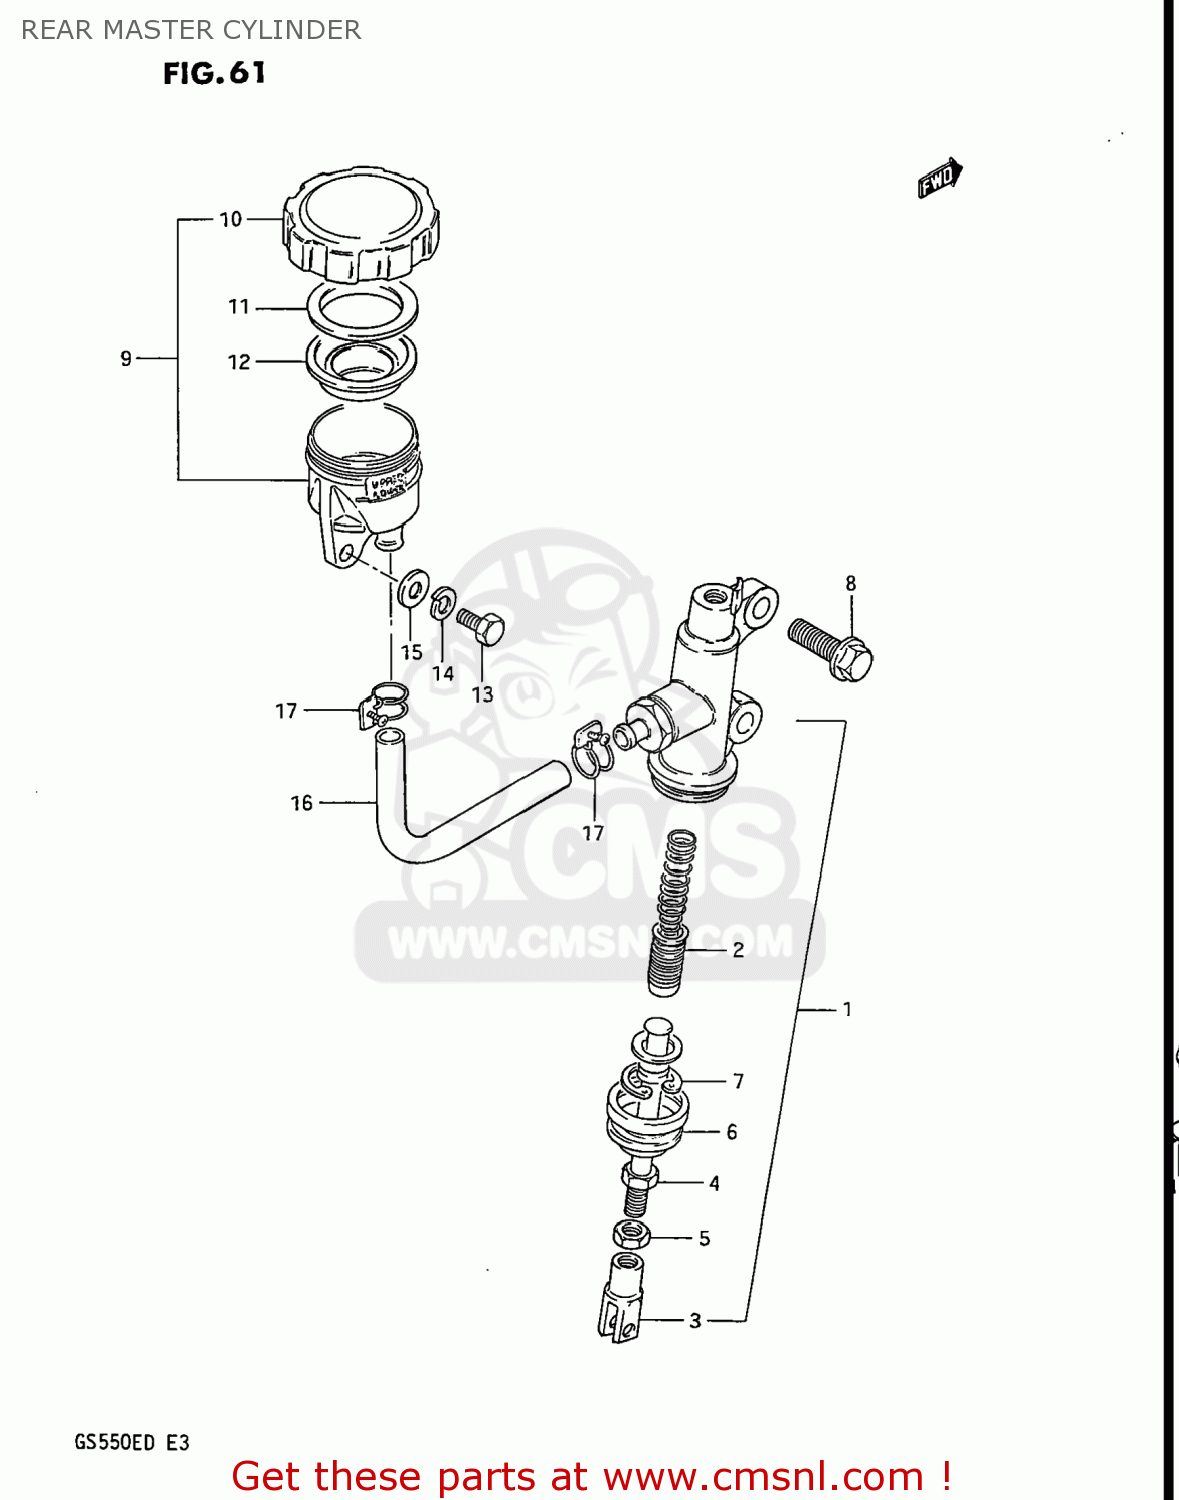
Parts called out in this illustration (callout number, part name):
1	CYLINDER ASSEMBLY,REAR MASTER
2	PISTON/CUP SET
3	YOKE
4	ROD,PUSH
5	NUT,MASTER CYLINDER
6	BOOT
7	CIRCLIP
8	BOLT
9	TANK ASSEMBLY,RESERVOIR
10	CAP
11	PLATE,DIAPHRAGM
12	DIAPHRAGM
13	BOLT, UPPER
14	LOCK WASHER
15	WASHER
16	HOSE,RESERVOIR TANK
17	CLAMP
